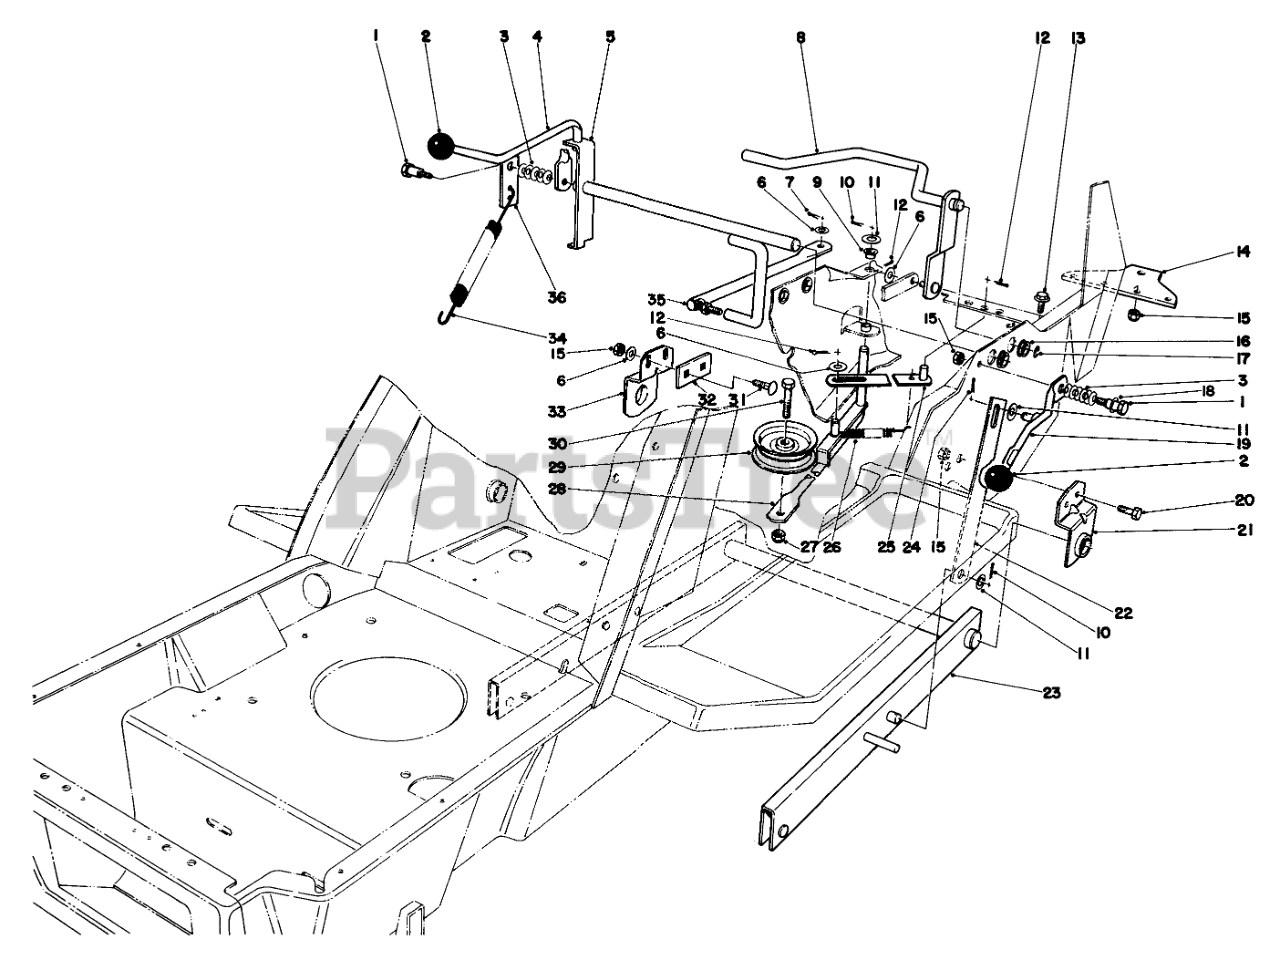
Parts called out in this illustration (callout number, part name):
1	BOLT-SHOULDER
3	WASHER-BELLEVILLE
4	SHIFT LEVER BO
5	Shim Lever
6	WASHER-PLAIN
7	PIN-COTTER
8	CLUTCH ACTUATOR WA B
9	BUSHING-NYLINER
10	PIN-COTTER
11	WASHER-FLAT
12	PIN-COTTER
13	SCREW-HHF
14	HITCH PLATE R
15	NUT-LOCK, CONE
16	Nyliner
17	E-RING
18	WASHER-FLAT
19	HOC HANDLE WA B
20	SCREW-HH
21	LH PIVOT BAR RET B
22	H.O.C. STRAP B
23	Bar-Pivot
24	PIN-COTTER
25	SPRING RET WA B
26	DECK TENSION SPRNG O
27	NUT-LOCK, CONE
28	IDLER ARM WA BO
29	IDLER PULLEY
30	SCREW-HH
31	BOLT-CARR
32	SPACER
33	RH PIVOT BAR RET B
34	TRACTION SPRING
35	SHIFT ARM BO
36	BRKT-COBALANCE SPRING
